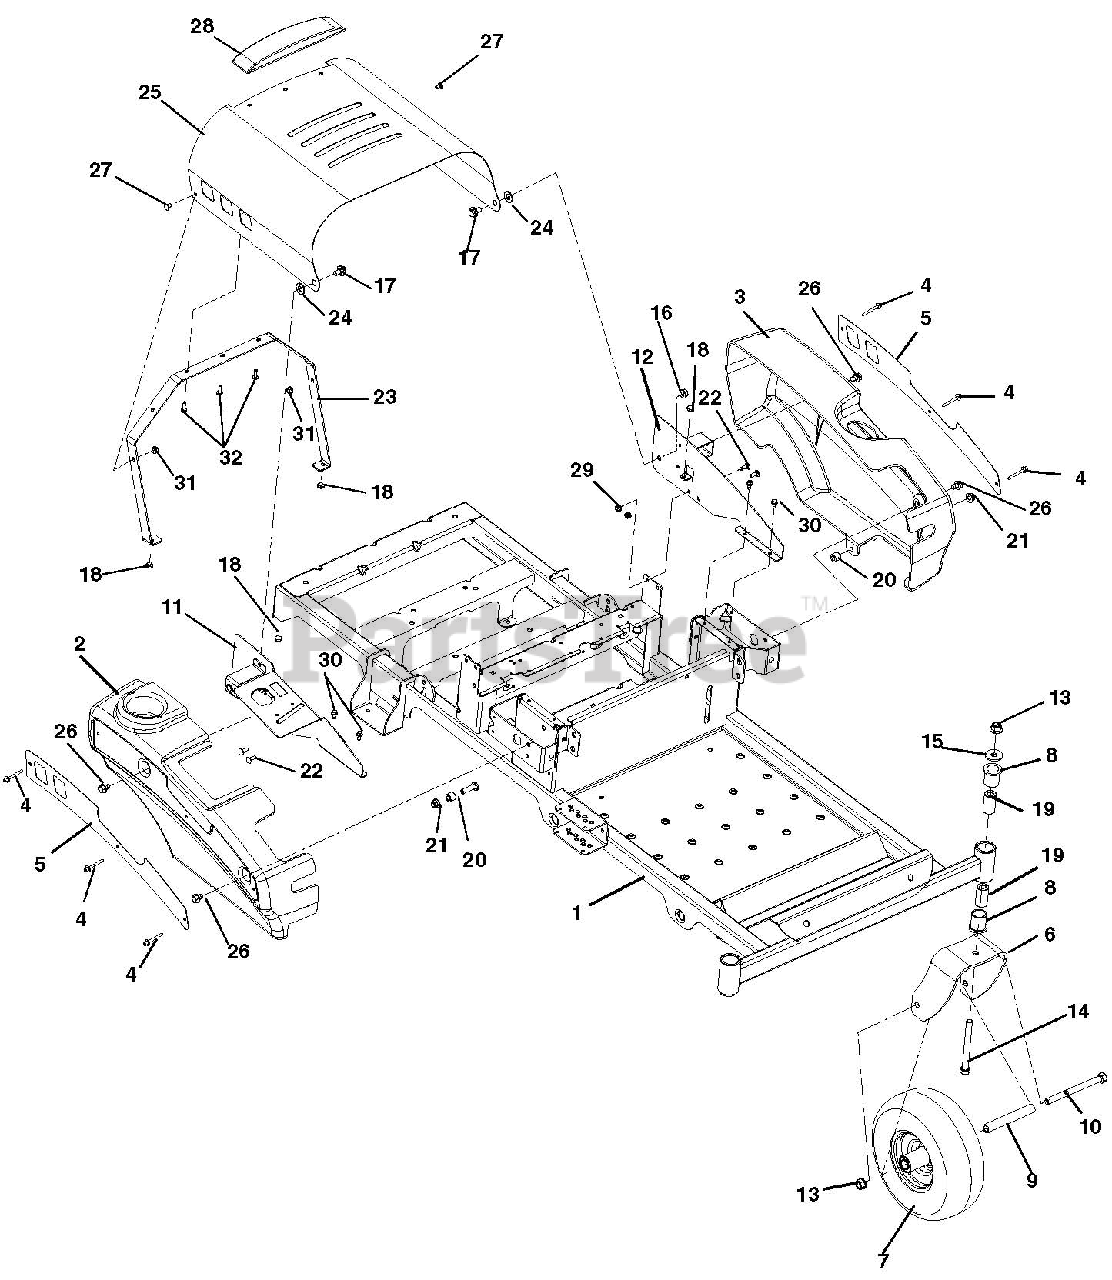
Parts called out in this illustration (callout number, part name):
1	WMT, FRAME BBZ
2	FENDER, RH
3	FENDER, LH
4	RIVET, NYLON (.219 HOLE .25TH)
5	PLATE, FENDER RH
6	CASTER FORK WELDMENT
7	TIRE/WHL ASM, FRONT
8	BSHG-FLG 1.00X1.25X1.50X1.50EP
9	SPACER, ROLLED WHEEL
10	@BLT-HEX .50-13X6.50 GR5 YWZC
11	WMT, FENDER MOUNT RH
12	WMT, FENDER MOUNT LH
13	@NUT-LK-TOP-FLG .50-13 YWZC
14	@BLT-HEX .50-13X5.00 GR5 YWZC
15	WSHR-FL-STL.511X1.441X.125 YWZ
16	@NUT-LK-TOP-FLG .38-16 YWZC
17	BOLT-SHLDR .375-16X.150
18	BUMPER GROMMET
19	SPACER, CASTER .50X1.00X1.84
20	BSHG-SLV .391X.688X.52 PM
21	@NUT-LK-NYL-FLG .38-16 YWZC
22	@BLT-RDHDSQNK .25-20X.75 G5YZ
23	BRACE, BBZ HOOD
24	WSHR-FL-NYL .518X1.000X.080
25	HOOD, BBZ
26	@SCR-TAP .38-16X.50 HWH TR YWZ
27	@BLT-RDHDSQNK .25-20X.50 G5YZ
28	TRIM-HOOD, ARIENS SMALL
29	@NUT-LK-NYL-FLG .25-20 YWZC
30	@SCR-TAP .25-20X.50 HWH TR YWZ
31	@NUT-LK-TOP-FLG .25-20 YWZC
32	SCREW,PHLPS PAN HEAD 12-11X5/8
